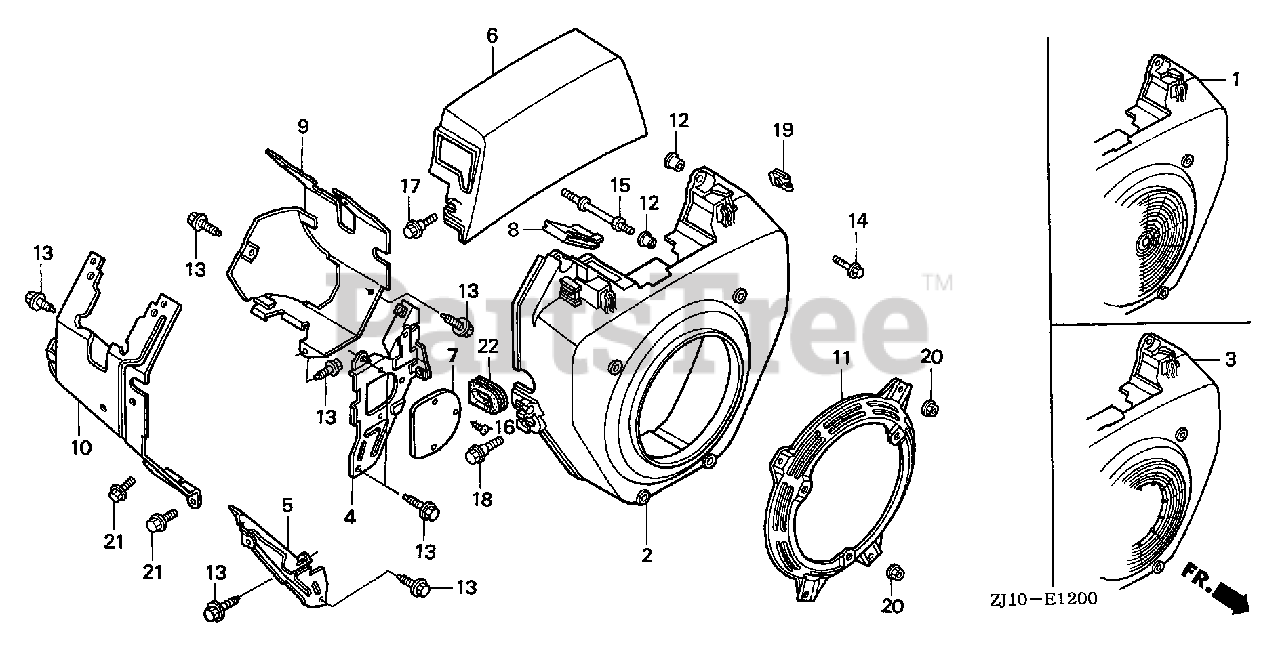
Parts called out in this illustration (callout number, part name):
1	COVER, FAN *NH1* (BLACK) (NA USE ALT:19611-ZJ1-820)
4	PLATE, SIDE
5	PLATE, SIDE
6	HOOD, FAN COVER
8	PLUG, FAN COVER HOLE
9	SHROUD (R.) (NOT AVAILABLE)
10	SHROUD (L.)
12	COLLAR B, TAILLIGHT
13	BOLT, FLANGE (6X12) (CT200)
14	BOLT, FLANGE (6X23) (CT200)
15	BOLT, STUD (6X73)
17	BOLT, FLANGE (6X20)
18	BOLT, FLANGE (6MM) (BLACK)
19	NUT, SPRING (6MM)
20	NUT, FLANGE (6MM)
21	BOLT, FLANGE (6X8)
22	GROMMET, CORD
